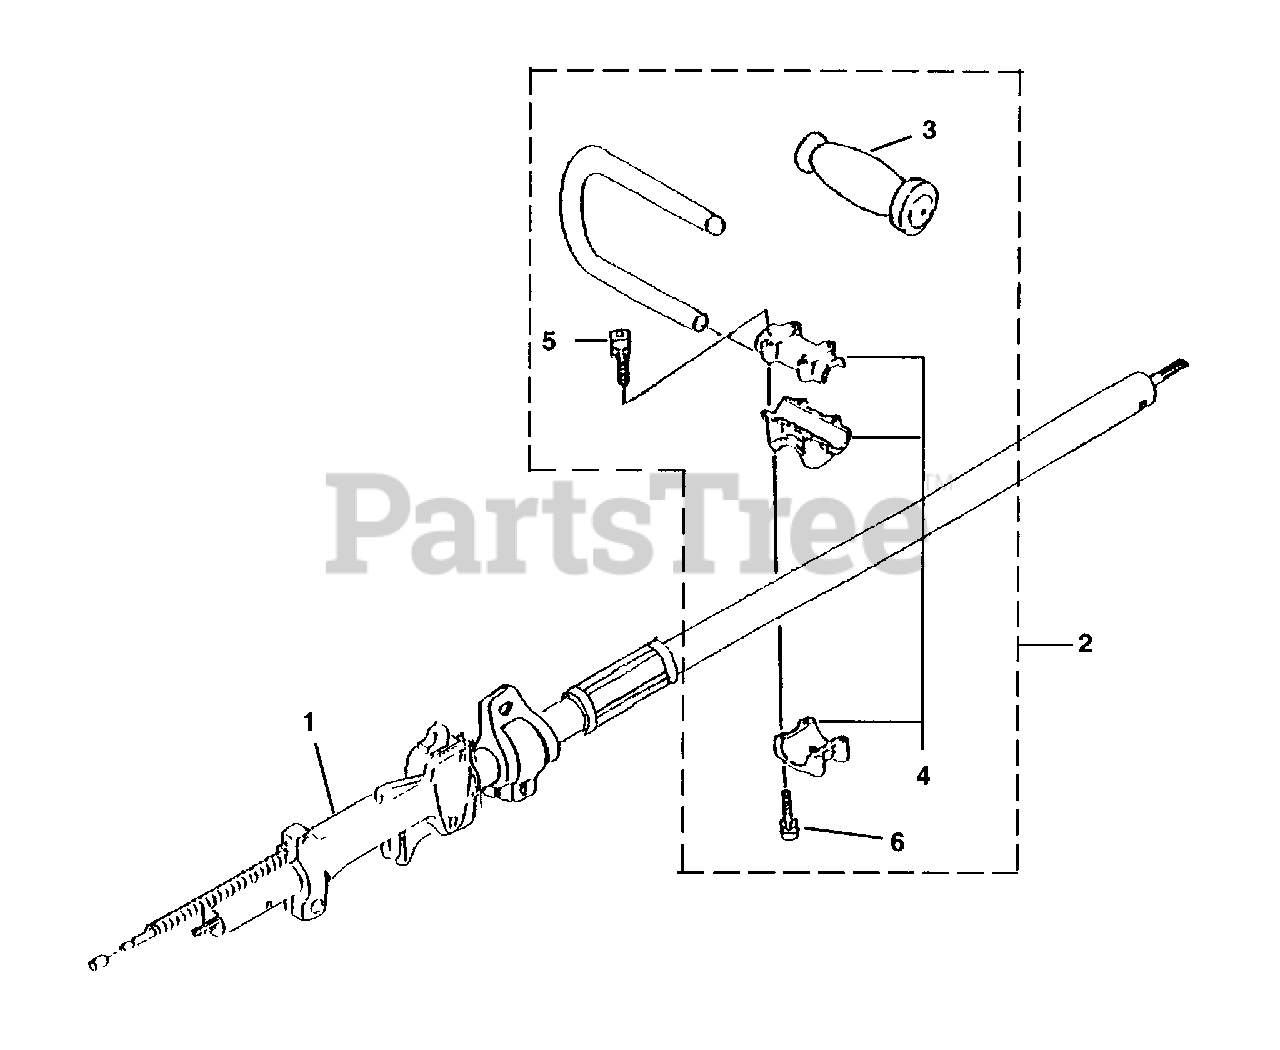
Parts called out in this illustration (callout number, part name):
1	CONTROL LEVER ASSEMBLY
2	HANDLE ASSEMBLY
4	HANDLE-Bracket Assembly
5	BOLT-Socket Hd (M5 x 25 SW)
6	BOLT-Socket Hd (M5 x 25 SW)
